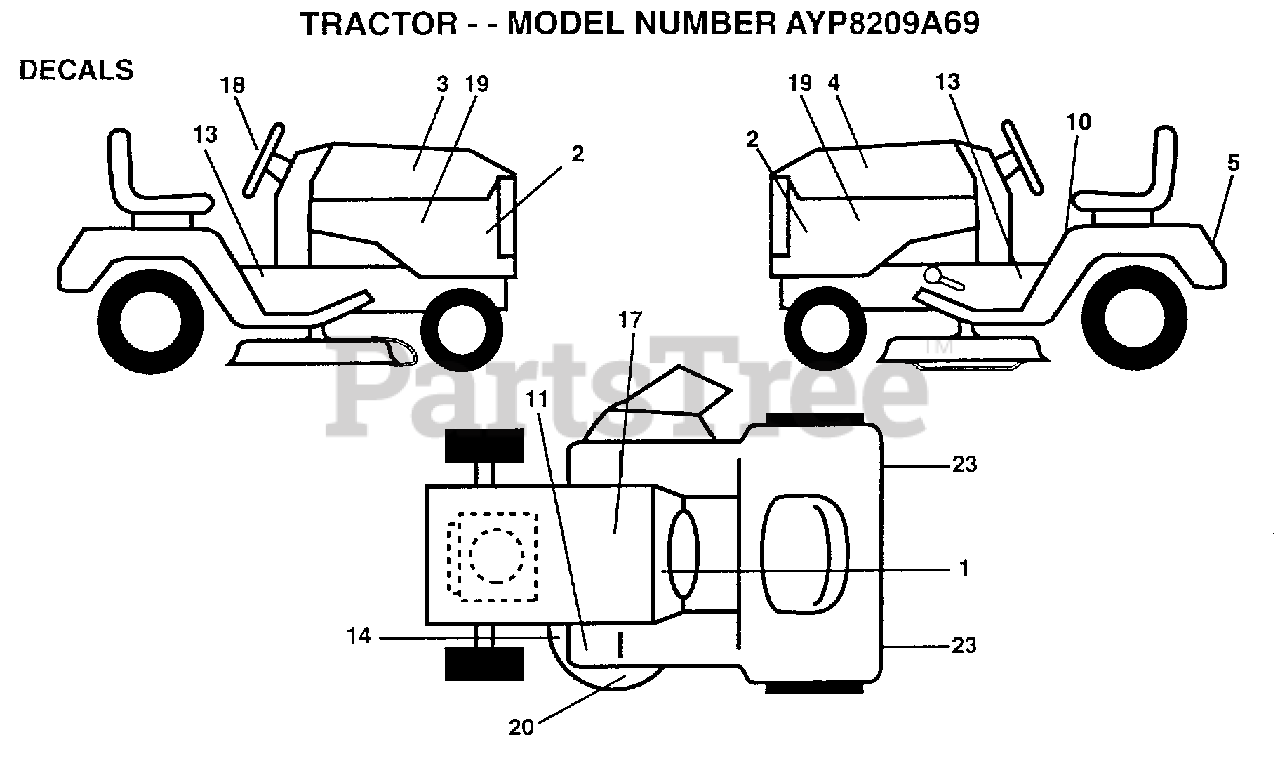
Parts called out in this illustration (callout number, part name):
1	DECAL.DASH.INST.
2	NAMEPLATE.HD.WIZA
3	DECAL.HD.RH.WIZRD
4	DECAL.HD.LH.WIZRD
10	DECAL
13	"DCL.CHASSIS.50"""
14	"DECAL.V.BELT.44"""
17	DECAL.BATRY.3-3908
18	DECAL INS STG WHL
19	"DECAL,PNL SIDE BS"
20	DECAL DECK WIZ +
23	REFLECTOR-TAIL YT
